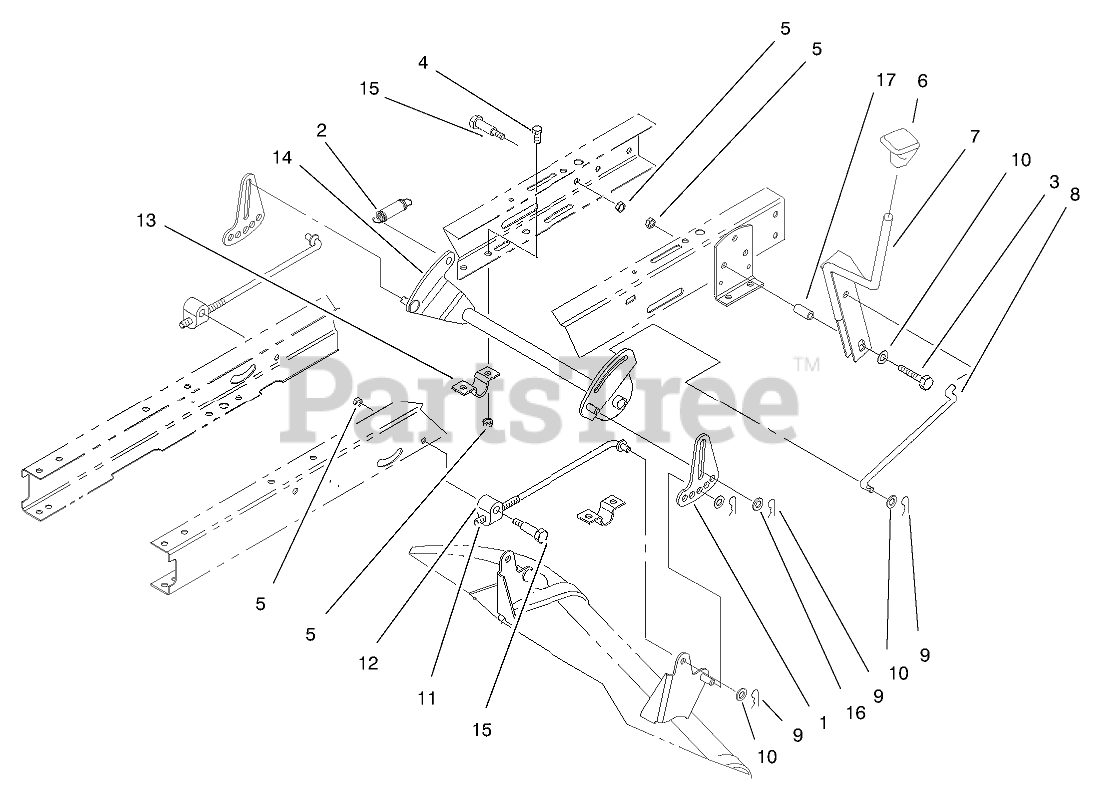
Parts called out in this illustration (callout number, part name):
1	Link-Adjusting H.O.C
2	SPRING-EXTENSION
3	SCREW-HH
4	SCREW-HH
5	NUT-LOCK, NI
6	KNOB-SHIFT
7	Lever-H.O.C.
8	LINK-HOC
9	PIN-COTTER
10	WASHER-FLAT
11	ROD-HANGER, REAR
12	TRUNNION-HOC
13	CLAMP-PIVOT, HOC
14	Pivot-H.O.C.
15	SCREW-SHOULDER, HH
16	WASHER-HARDENED
17	SPACER
